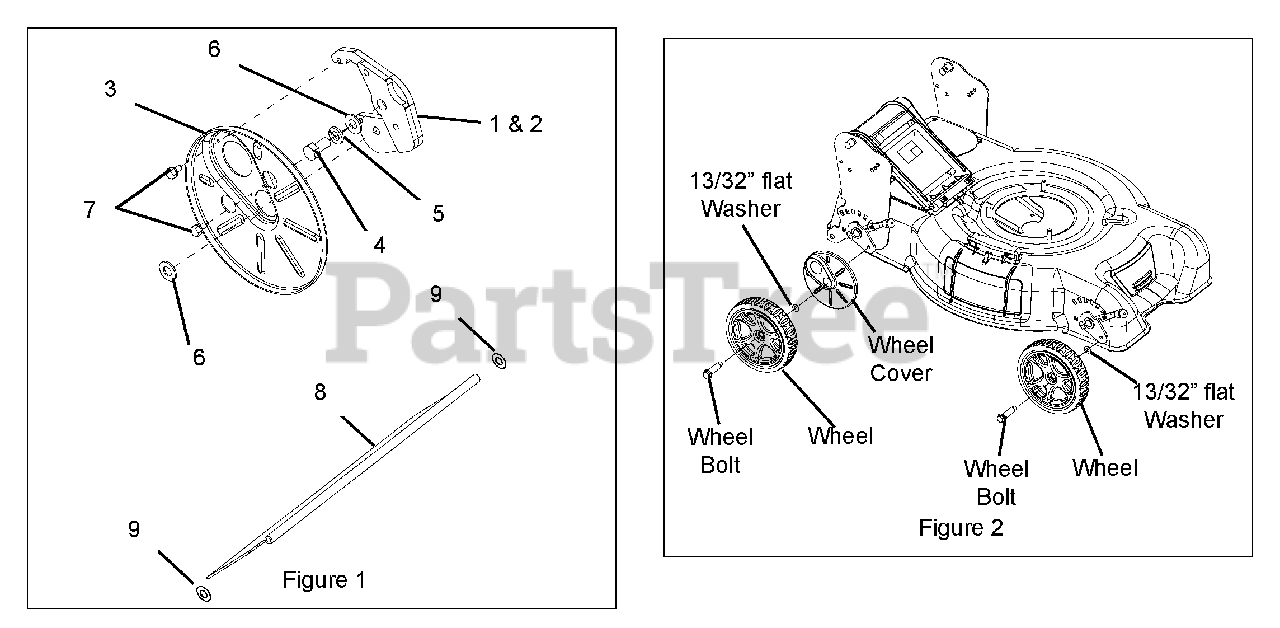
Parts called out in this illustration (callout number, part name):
1	BRKT, FLORIDA HOC EXT LH
2	BRKT, FLORIDA HOC EXT RH
3	WHEEL COVER, HOC EXT KIT
4	@BLT-HEX .38-16X.75 GR5 YWZC
5	@WSHR-LK .38X.094 REG YWZC
6	@WSHR-FL-STL.406X.812X.065 YWZ
7	@SCR-TAP 10-24X.375 HWH YZ TR
8	GUARD, WBLM
9	RETAINER, .38 PUSH-ON
